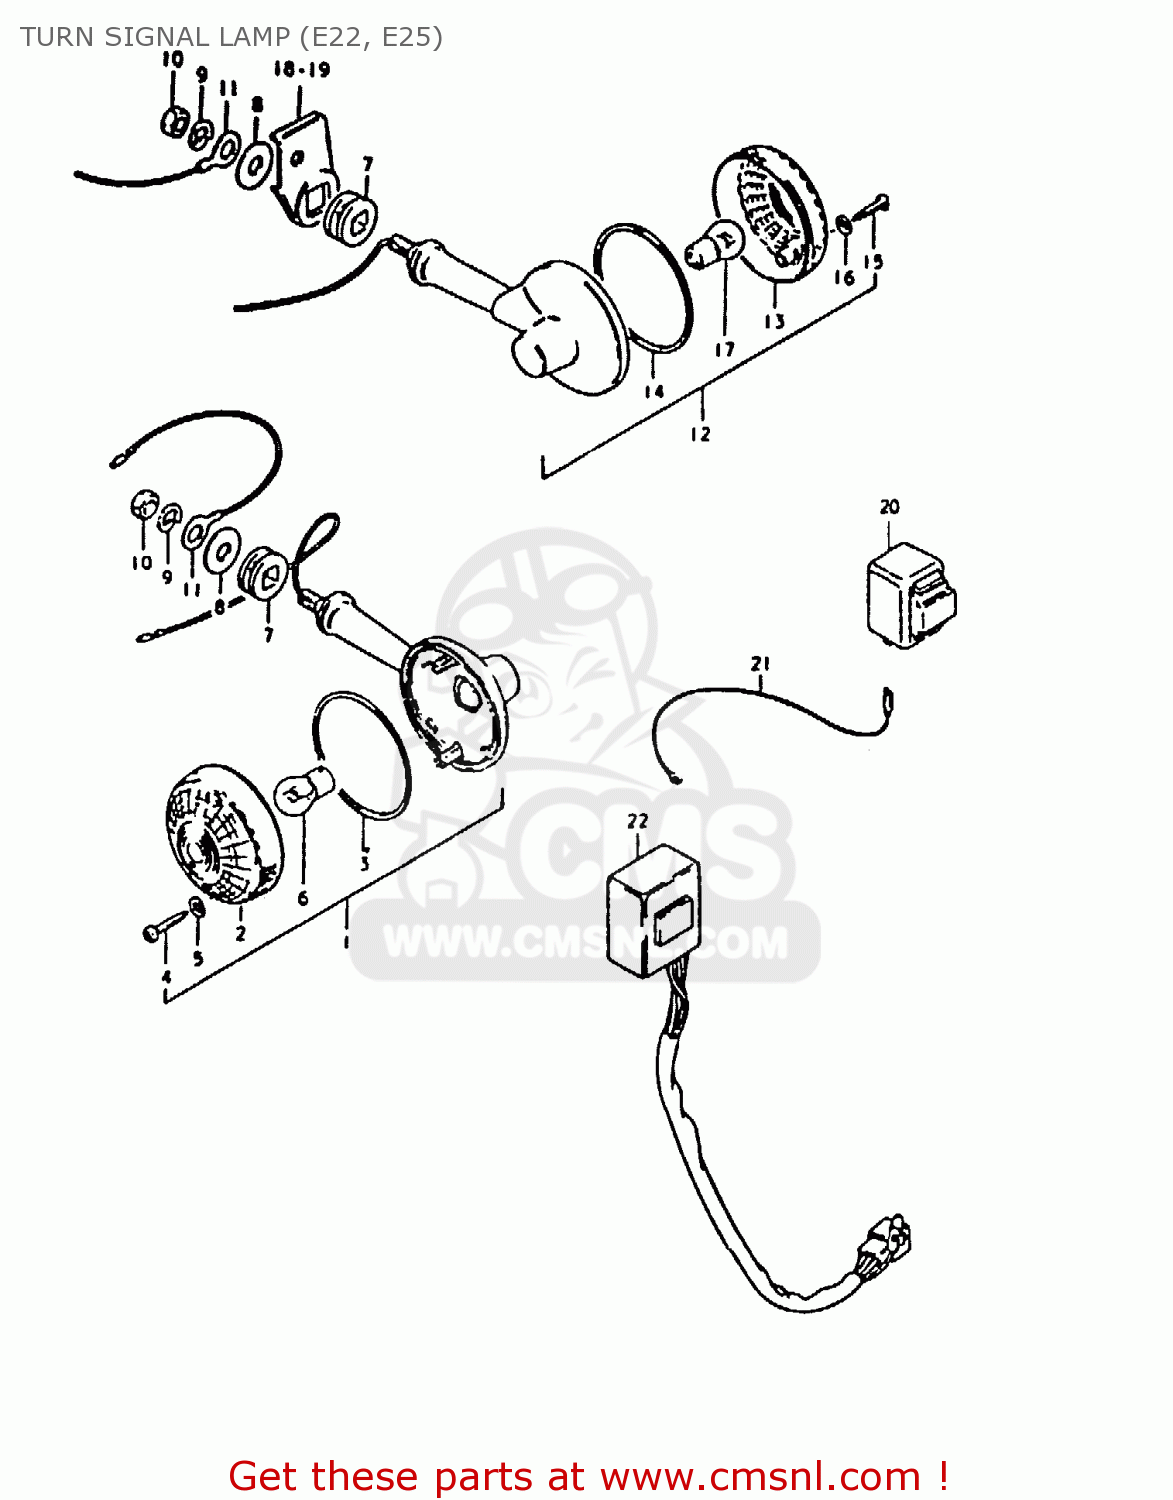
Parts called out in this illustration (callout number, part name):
1	LAMP, REAR TURN SIGNAL
2	LENS
3	GASKET (NAS)
4	SCREW (4X30)
5	GASKET (NAS)
6	BULB(12V21W)
7	CUSHION
8	WASHER (10.5X30X2.3)
9	LOCK WASHER
10	NUT
11	LEAD WIRE,EARTH
12	LAMP, REAR TURN SIGNAL
13	LENS
14	GASKET (NAS)
15	SCREW (4X30)
16	GASKET (NAS)
17	BULB(12V21W)
18	BRACKET,RR TURNSIGNAL LAMP,R
19	BRACKET,RR TURNSIGNAL LAMP,L
20	RELAY, TURN SIGNAL
21	LEAD WIRE, RELAY EARTH
22	UNIT,TURN SIGNAL CONTROL
